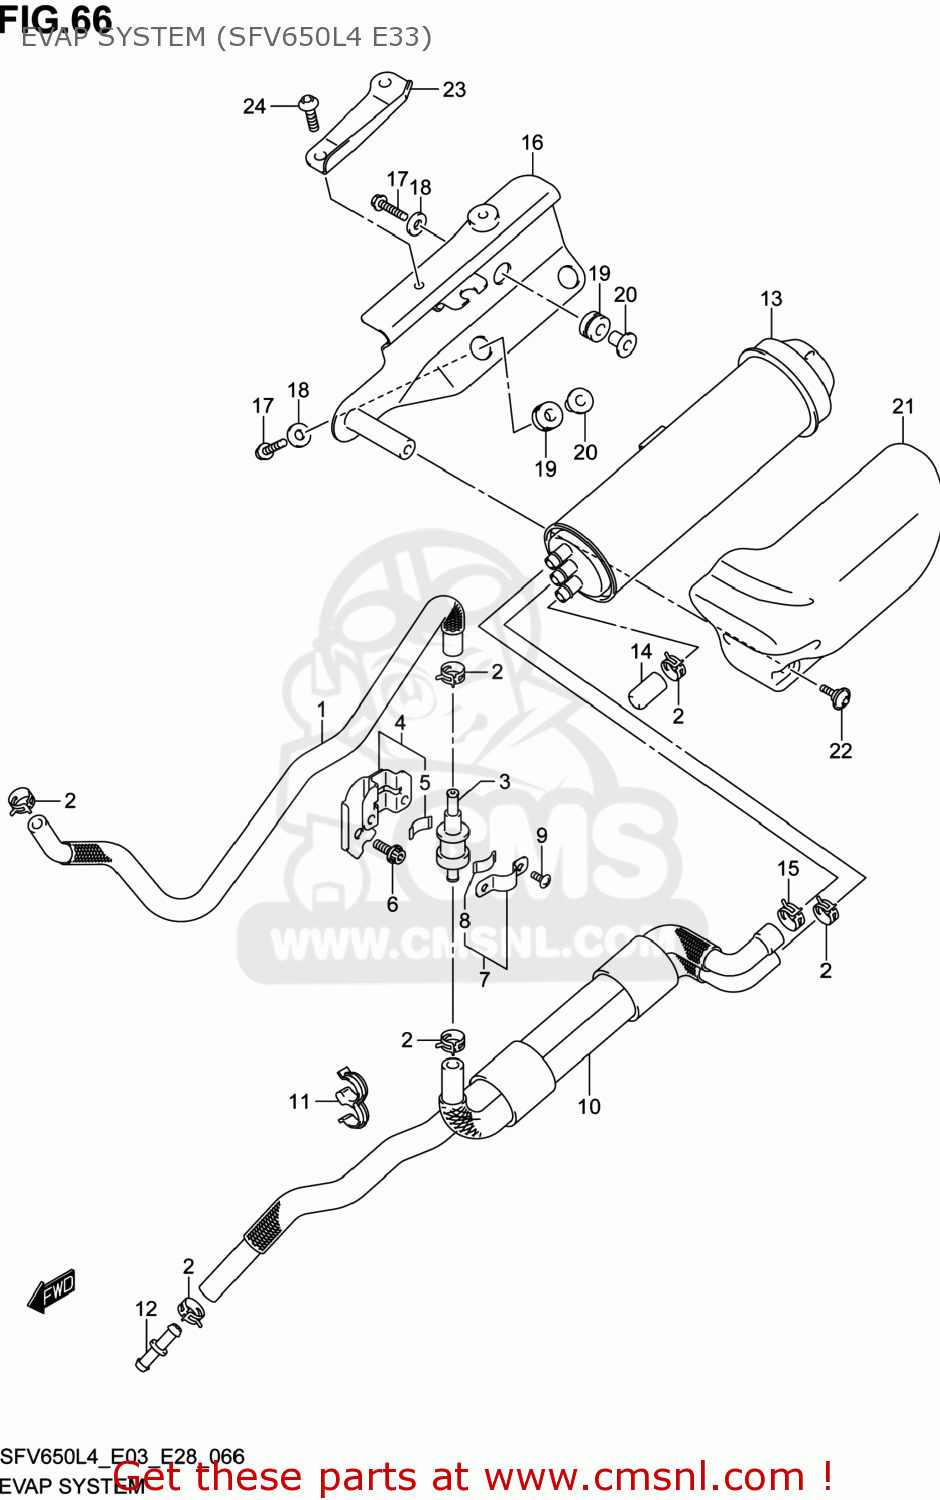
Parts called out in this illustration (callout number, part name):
1	HOSE,TANK & BREATHER VALVE
2	CLIP
3	VALVE,FUEL TANK BREATHER
4	BRACKET,BREATHER VALVE
5	CUSHION
6	BOLT
7	PLATE,FUEL TANK BREATHER NO.2
8	CUSHION
9	SCREW
10	HOSE,CANISTER
11	CLAMP
12	JOINT
13	CANISTER SET
14	CAP,OD:11.5
15	CLIP
16	BRACKET,CANISTER
17	BOLT
18	WASHER(6.5X16X3.2)
19	CUSHION
20	WASHER
21	COVER,CANISTER
22	SCREW(5X13)
23	BRACKET,CANISTER NO.2
24	SCREW(6X25)
